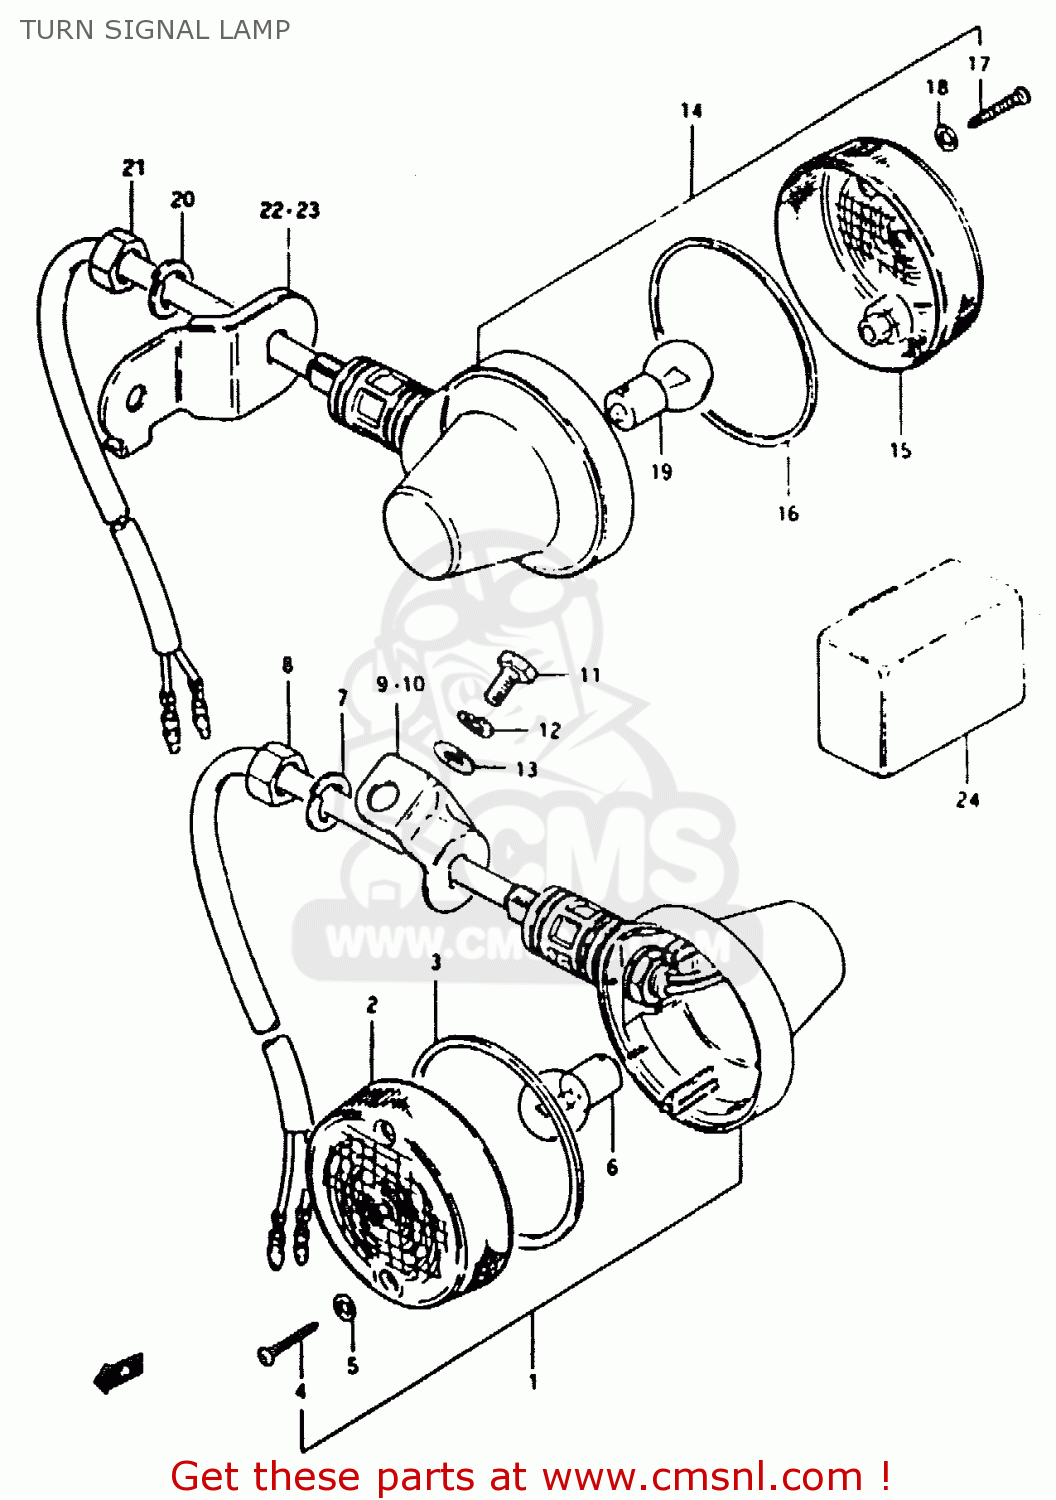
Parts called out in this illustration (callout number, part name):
1	LAMP ASSY,RR TURNSIGNAL
2	LENS
3	GASKET (NAS)
4	SCREW TAPP.
5	GASKET (NAS)
6	BULB (6V,18W)
7	WASHER,LOCK 12
8	NUT
9	BRACKET,TURNSIGNAL LAMP,R
10	BRACKET,TURNSIGNAL LAMP,L
11	BOLT
12	LOCK WASHER
13	WASHER
14	LAMP ASSY,RR TURNSIGNAL
15	LENS
16	GASKET (NAS)
17	SCREW TAPP.
18	GASKET (NAS)
19	BULB (6V,18W)
20	WASHER,LOCK 12
21	NUT
22	BRACKET,REAR TURN SIGNAL
23	BRACKET,REAR TURN SIGNAL
24	RELAY,TURN SIGNAL
